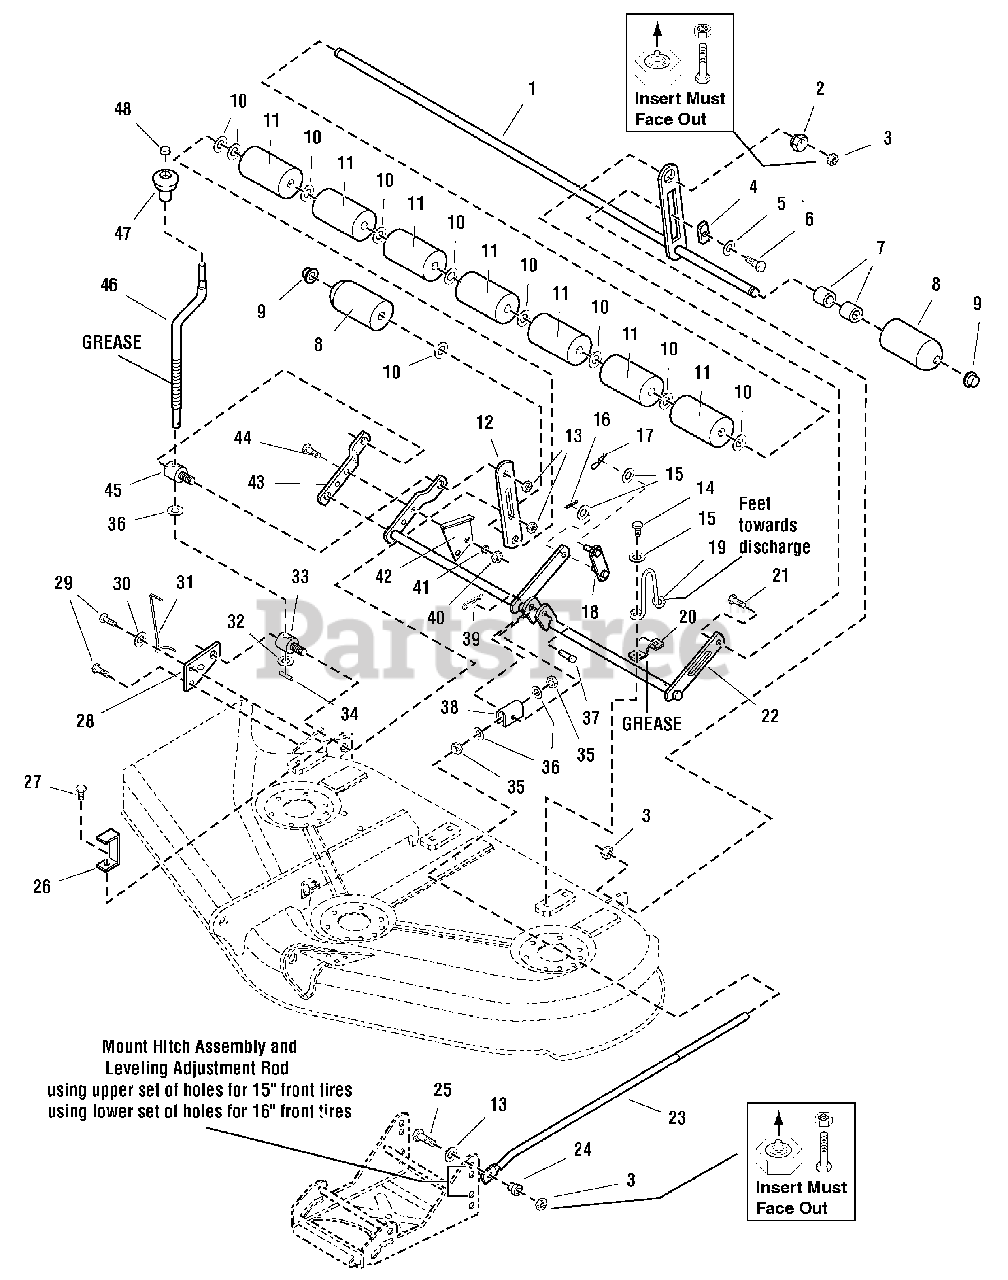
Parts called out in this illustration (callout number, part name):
1	SHAFT & BAR ASSEMBLY, 44" (Includes Ref. No. 9)
2	NUT, Adjuster
3	NUT, Toplock Spiral Flange, 3/8-16
4	SLIDE
5	WASHER, Plain, 1/2
6	BOLT, Shoulder, 3/8-16
7	SPACER, 25/64 x 13/16 x 13/16, Steel, Black
8	ROLLER, Rounded, 2-1/2 Long
9	NUT, Push
10	WASHER, Plain, 1-1/4
11	ROLLER
12	BAR, Roller
13	NUT, Hex, Flange, Lock, 1/2-13
14	CAPSCREW, Hex Head Taptite, 5/16 -18 x 3/4
15	WASHER, 3/8
16	PIN, Cotter
17	RETAINER, Pin, Spring
18	BRACKET & PIN ASSEMBLY
19	UPSTOP
20	STRAP, Mower Arm Assembly
21	CARRIAGE BOLT, 3/8-16 x 1-1/2
22	ARM ASSEMBLY, Mower
23	ROD, Adjustment
24	SPACER, 3/8 x 3/4 x 15/16
25	CAPSCREW, Hex Head, 3/8-16 x 1-3/4
26	BRACKET, Upstop
27	CAPSCREW, Hex Washer Head Taptite, 5/16-18 x 1, Black
28	PLATE, Mower Support
29	CAPSCREW, Hex Head Taptite, 5/16-18 x 1-1/4
30	WASHER, 5/16, Black
31	INDICATOR, Height of Cut
32	WASHER, Detent
33	TRUNNION
34	PIN, Roll, 1
35	NUT, Hex, Jam, 1/2-13
36	WASHER, 33/64
37	PIN, Clevis
38	TRUNNION
39	CLIP, Hair Pin
40	NUT, Hex, 5/16-18
41	WASHER, Lock, 5/16
42	BRACKET, Height of Cut
43	ARM, Rear, Mower, RH
44	CAPSCREW, Hex Head, 5/16-18 x 1-1/4
45	TRUNNION, Threaded
46	CRANK, Height of Cut
47	KNOB, Height Crank
48	PAL NUT
